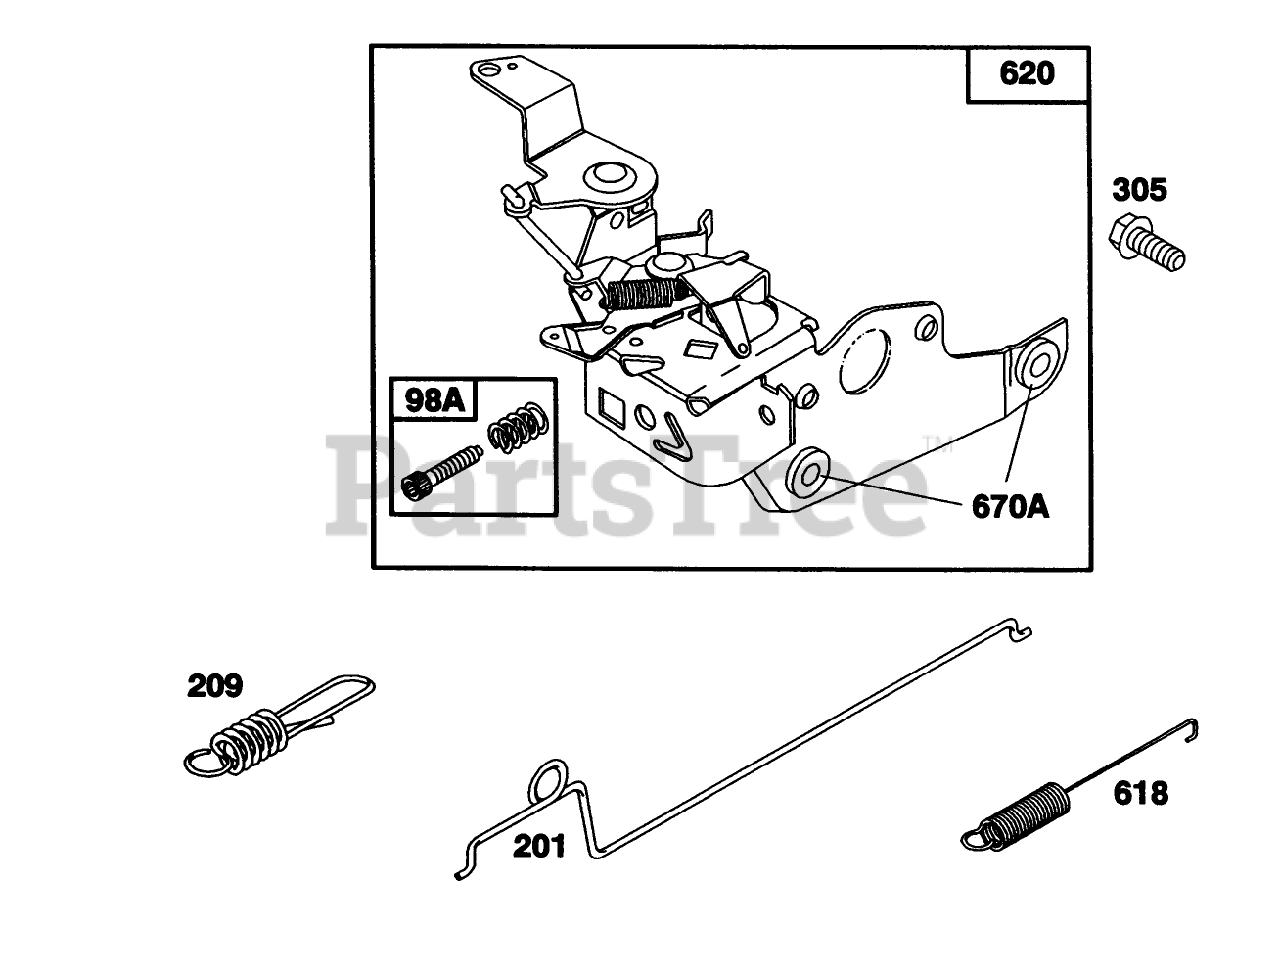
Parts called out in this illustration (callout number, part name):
98A	Screw Assy.
201	Link-Govemor
209	Spring-Govemor
305	Screw-Sem
618	Spring-Choke
620	Bracket Assembly
670A	Spacer
